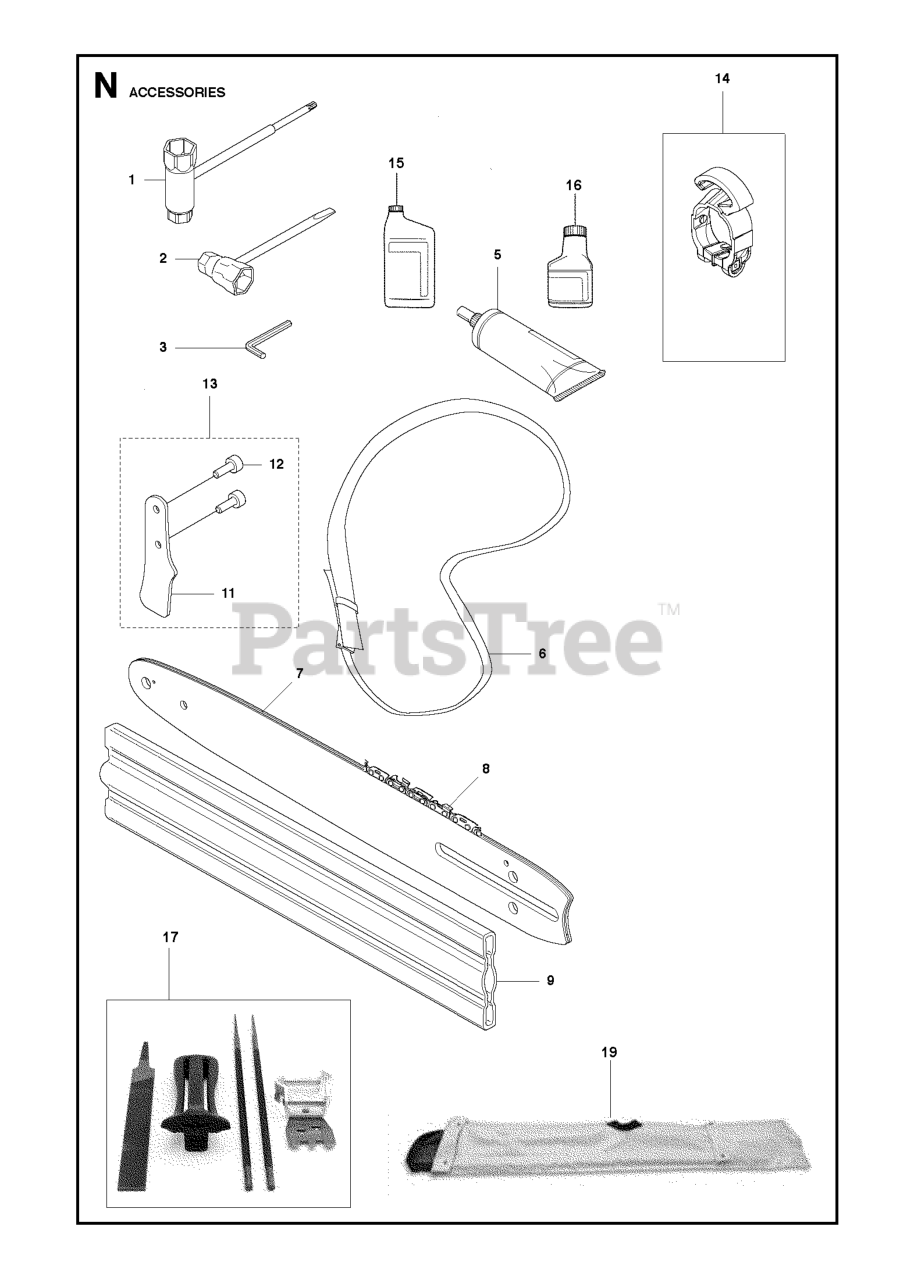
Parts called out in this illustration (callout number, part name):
1	COMBINATION WRENCH TORX
2	COMBI TOOL
5	GREASE
6	HARNESS WITHOUT HOOK
7	HUS 12" BAR LAM 3/8MIN 050 44D
8	12" CHN S93G 3/8 MIN .050 44DL
11	SHEET HOOK
12	SCREW ITXSCM
13	HOOK
14	HARNESS BRACKET ASSY
15	BAR CHAIN OILS
16	OIL (BLUE CAP) XP 2.6 OZ
17	HUS FILE KIT 3/8 MINI (S93G)
